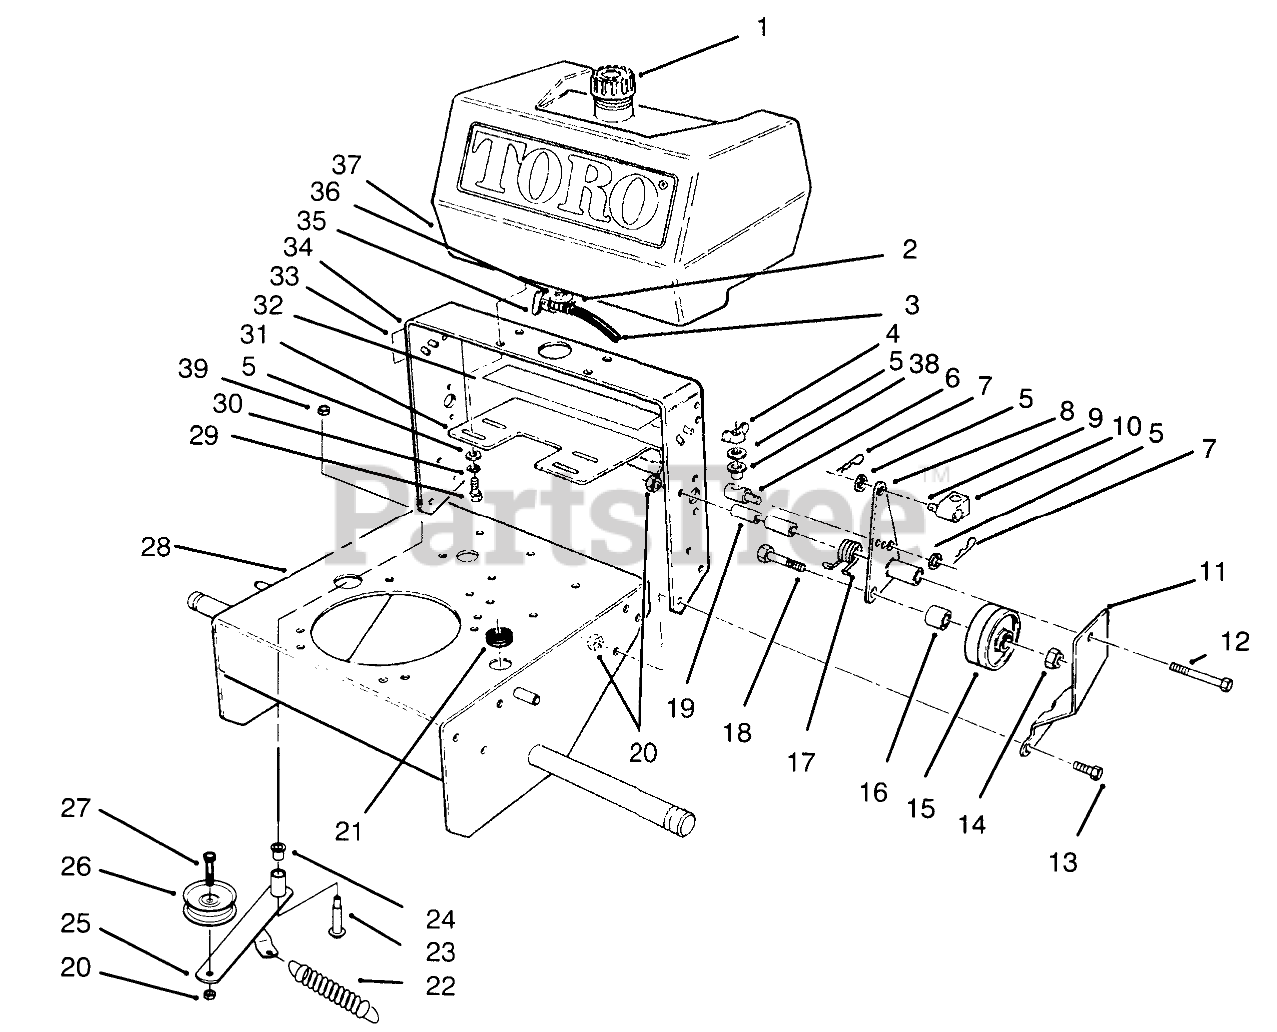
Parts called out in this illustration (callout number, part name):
1	GAS CAP ASM
2	CLAMP-HOSE
3	HOSE-FUEL
4	NUT-WING
5	WASHER-PLAIN
6	FITTING-ROD
7	PIN-COTTER
8	BRACKET-Idler, LH
9	PIN-CLEVIS
10	FITTING-ROD
11	Bracket-LH
12	SCREW-HH
13	SCREW-HH
14	NUT-LOCK, NI
15	IdlerWheel
16	WHEEL IDLER SPACER
17	SPRING-TORSION, LH
18	SCREW-LEVELER
19	SPACER-PIVOT, IDLER
20	NUT-LOCK, NI
21	GROMMET
22	SPRING
23	BOLT-WHEEL
24	BUSHING-FLANGE
25	Lever-Idler (Incl. Ref. #24)
26	PULLEY
27	SCREW-HH
28	Frame
29	SCREW-HH
30	WASHER-LOCK
31	Plate
32	DECAL-GROUND SPEED
33	DECAL-FUEL SHUT OFF
34	Frame Rear
35	VALVE-FUEL
36	O-RING
37	FUEL TANK
38	BUSHING-NYLON
39	NUT-LOCK
